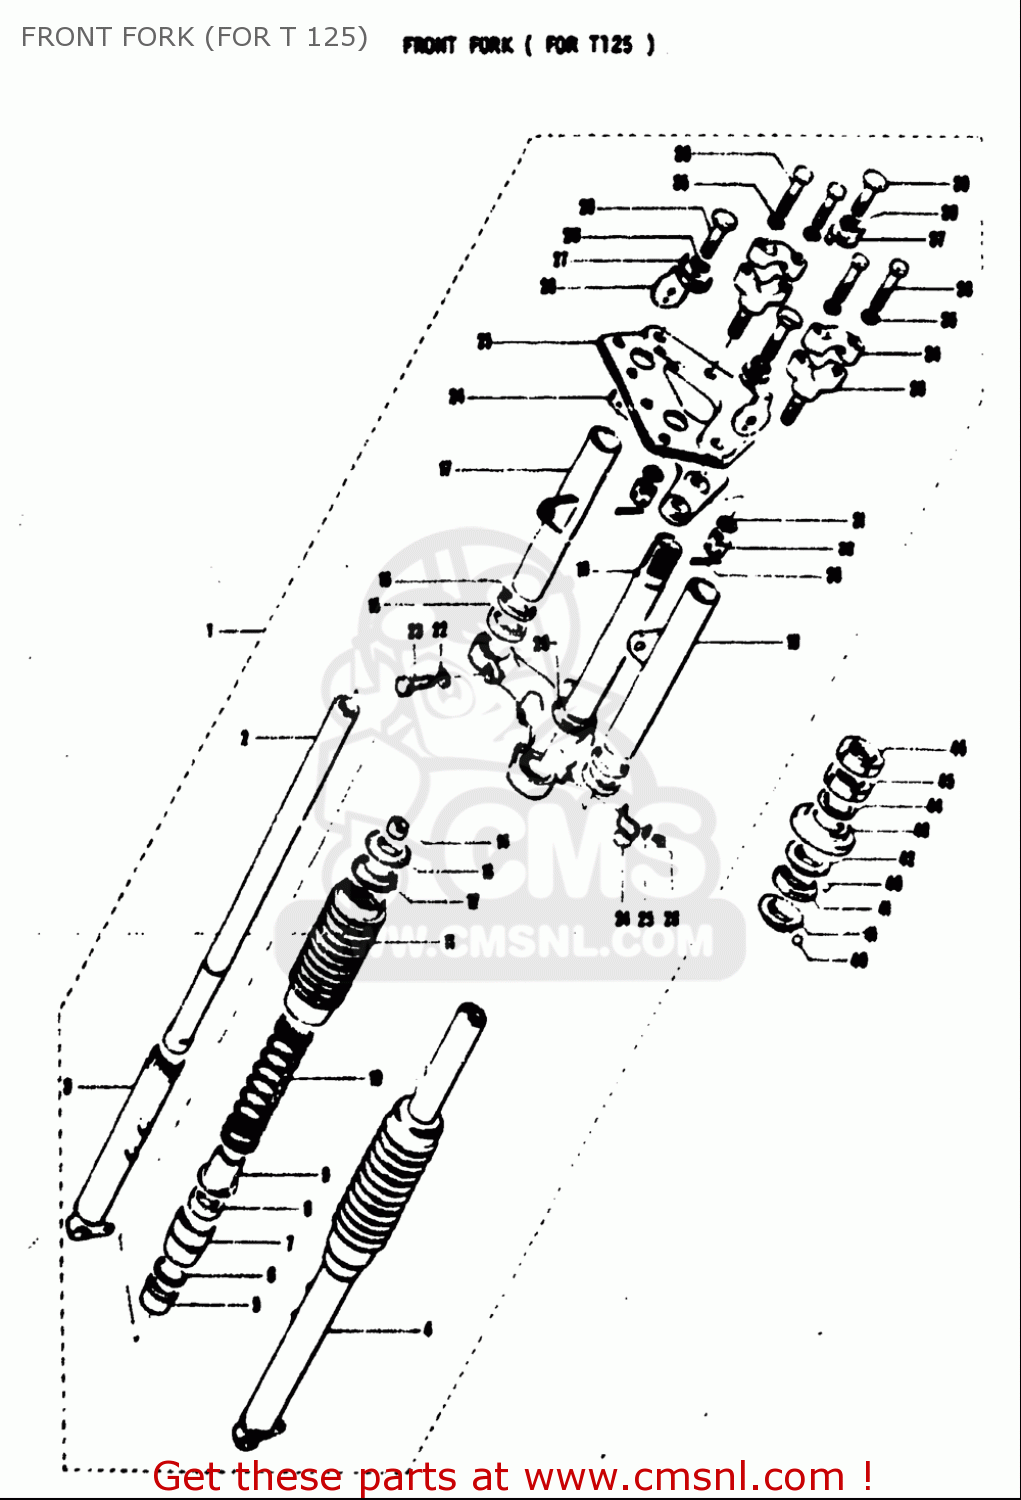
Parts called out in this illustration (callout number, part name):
5	GUIDE,FORK INNER TUBE
10	SPRING,FR FORK
21	CLIP,SPEEDOMETER CABLE
22	WASHER,LOCK
23	BOLT
28	WASHER,LOCK
31	WASHER,LOCK
32	NUT
33	PIN
34	HOLDER,HANDLEBAR
38	WASHER,LOCK
42	LACE,STEERING OUTER UPR
